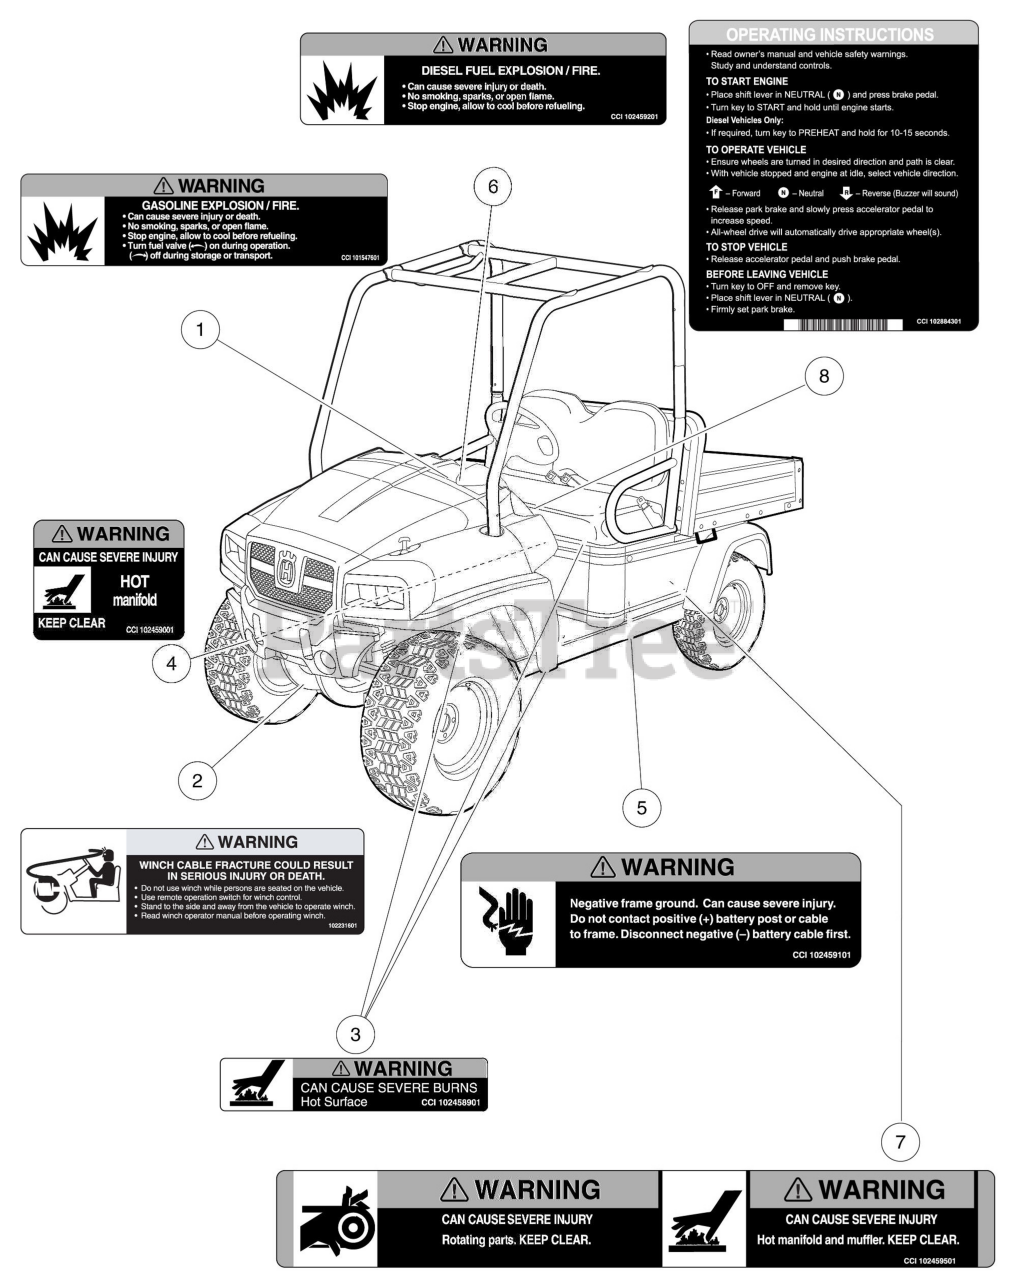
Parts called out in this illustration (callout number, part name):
1	Decal, Gasoline Explosion/Fire Warning
2	Decal, Winch Cable Fracture Warning
3	Decal, Hot Surface Warning
4	Decal, Hot Manifold Warning
5	Decal, Frame Ground Warning
6	Decal, Diesel Explosion/Fire Warning
7	Decal, Rotating Parts and Hot Exhaust Warning
8	Decal, Operating Instr, AWD
